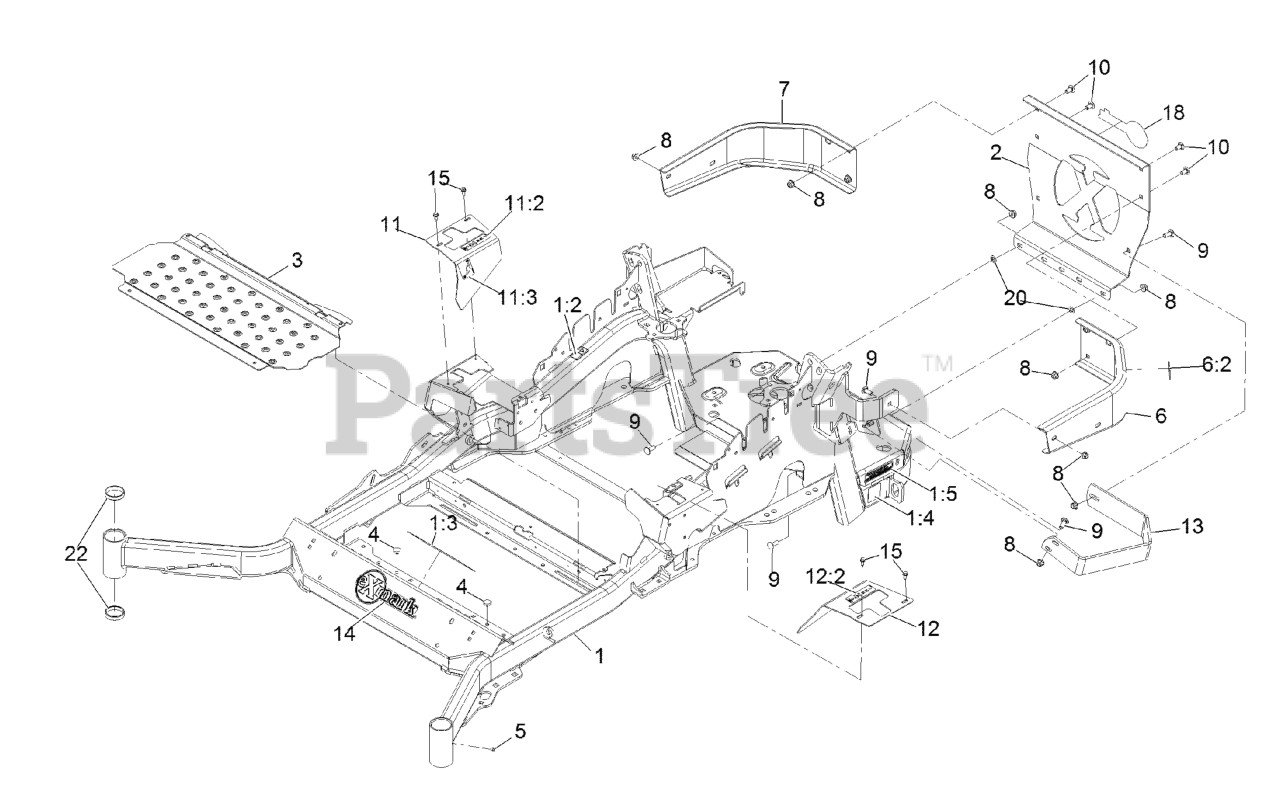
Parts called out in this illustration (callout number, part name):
1	MAINFRAME ASM
1:2	DECAL-WARNING
1:3	DECAL-DANGER
1:4	DECAL-HAZARD, PINCHED FINGER
1:5	DECAL-SPARK ARRESTER
2	PLATE,REAR GUARD
6	LH BUMPER ASM
6:2	DECAL-WARNING
7	BUMPER-RH
8	NUT-HF, NI
9	SCREW-CARR
10	SCREW-CARR
11	RH MOTION CONTROL COVER ASM
11:2	DECAL-CONTROL, MOTION
11:3	DECAL-PARK BRAKE, CE
12	LH MOTION CONTROL COVER ASM
12:2	DECAL-CONTROL, MOTION
13	GUARD-MUFFLER
14	DECAL-EXMARK LOGO
15	SCREW-HWH
18	DECAL-EXMARK LOGO
19	Decal-Patent Ttco.Com
20	NUT-PUSH
21	DECAL-FUEL FILL, CE
22	CUP-BEARING
